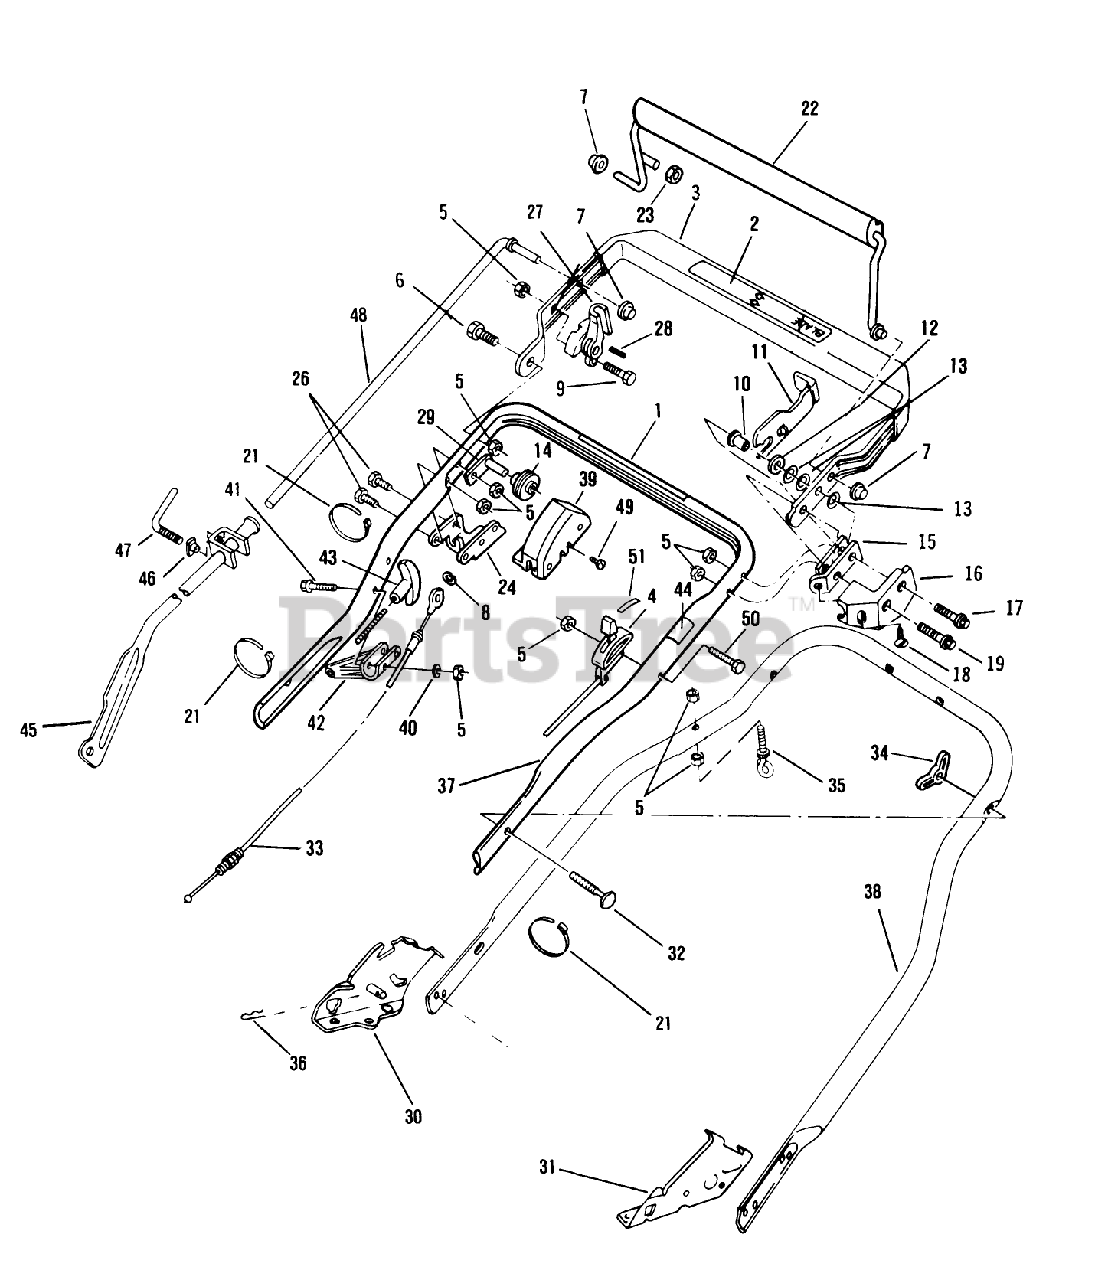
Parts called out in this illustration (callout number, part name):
4	CONTROL THROT WES
5	LOCKNUT E
6	BOLT
8	RET. RING
10	SPACER
12	WASHER M
14	PULLEY PL
15	DOWN STOP
16	LOCKOUT GUARD
17	BOLT SHOU
18	SCREW F
19	SCREW
23	NUT ACORN
30	BRACKET ASM - HANDLE, SP, RH
31	BRACKET ASM - HANDLE, SP, LH
32	BOLT QUALITY
33	CONTROL CABLE
34	NUT-WING
35	EYE BOLT WAS MFG
36	HAIR PIN
37	HANDLE SECTION
40	WASHER
43	HANDLE START UM&D
45	CONTROL LEVER AY
48	CONTROL ROD
